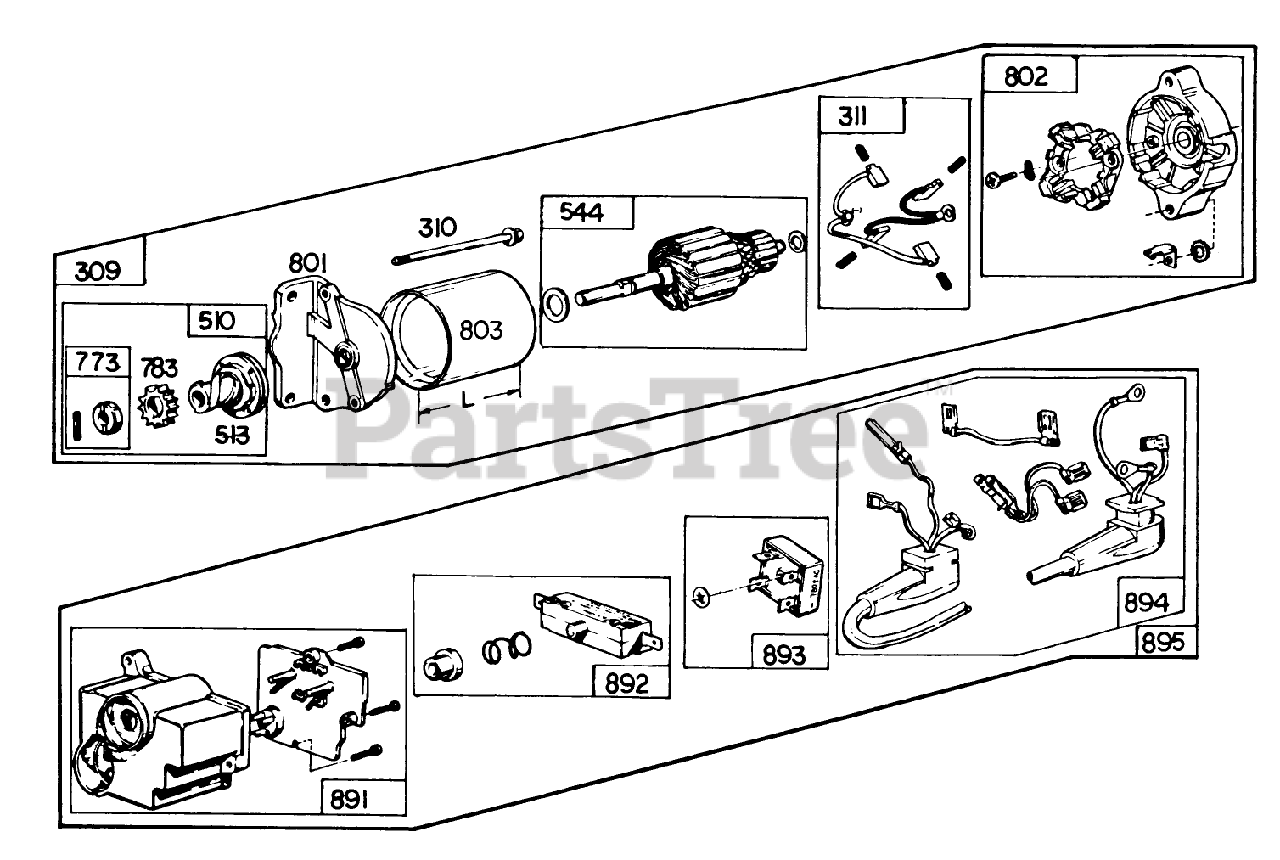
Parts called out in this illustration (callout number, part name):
309	Motor Drive Assembly
310	Thru Bolt Assembly
311	Brush Assembly
510	Drive Assembly
513	Clutch Assembly
544	Armature Assembly
773	Gear-Starter
801	Drive End Cap Assembly
802	Comm. End Cap Assembly
803	Housing Assembly
891	Housing Group
892	Switch Group
893	Rectifier
894	Lead Group
895	Control Group
